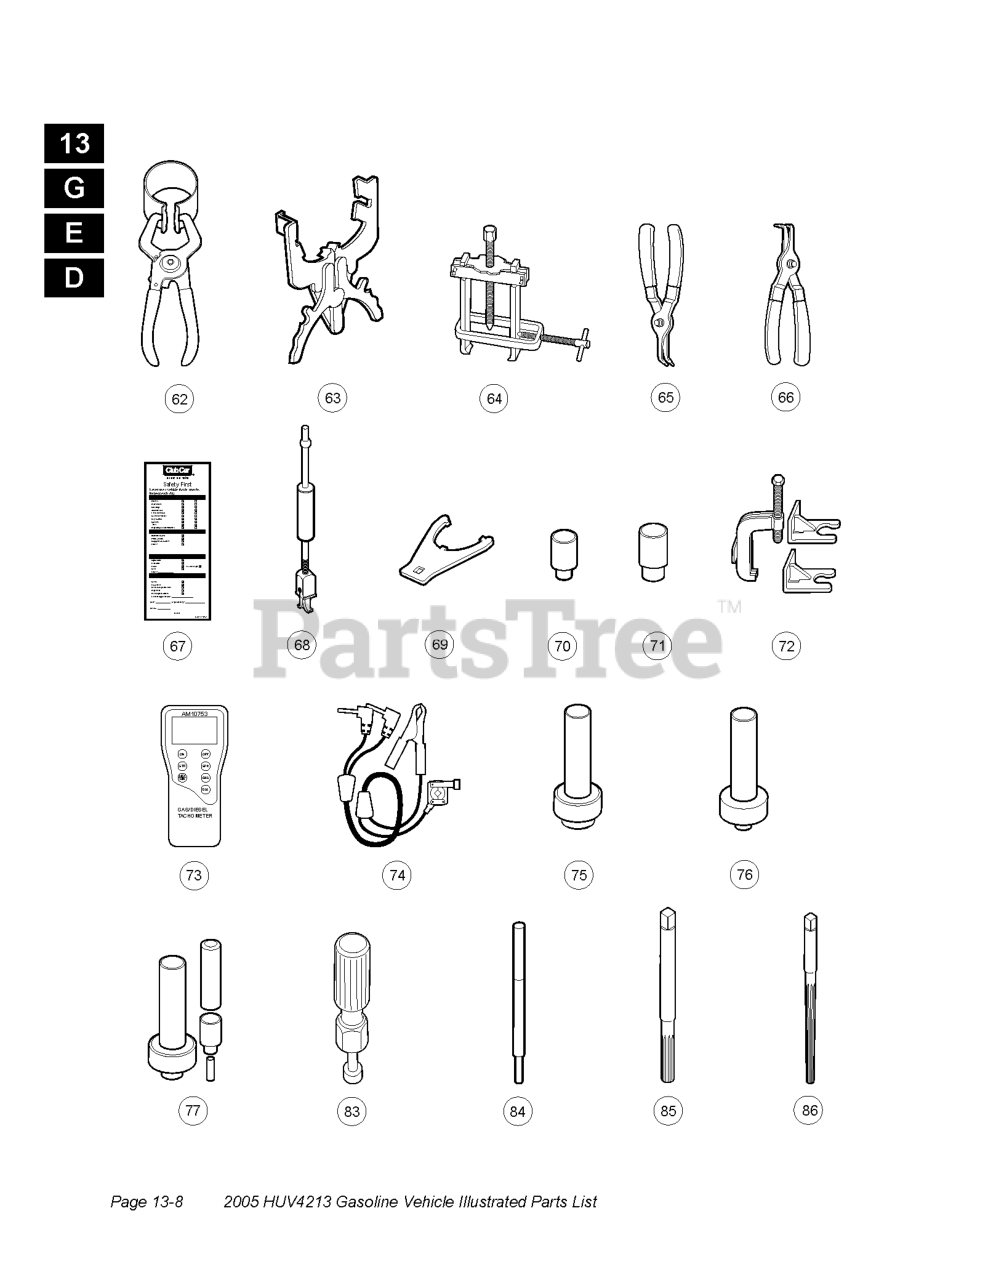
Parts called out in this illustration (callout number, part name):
62	KIT, PISTON RING COMPRESSOR
63	PISTON RING PLIER
65	EXTERNAL SNAP RING PLIERS
66	INTERNAL SNAP RING PLIER 9O
67	SAFETY FIRST CARD
68	SEAL PULLER
69	WRENCH, SPANNER
70	Steering Column Bearing Press Tool
71	TOOL-STEERING RETAINING RING
72	PULLER, STEERING WHEEL
73	TACHOMETER GAS/DIESEL
75	TRANS-AXLE, AXLE SEAL TOOL
76	Transaxle Pinion Seal Tool
77	Transmission Tool Kit
82	VALVE CLEAR ADJ SCREW HOLDER
83	DRIVER, VALVE GUIDE, 6.6. MM
84	VALVE GUIDE REAMER
85	REAMER-VALVE GUIDE
86	VALVE SEAT CUTTER GUIDE
